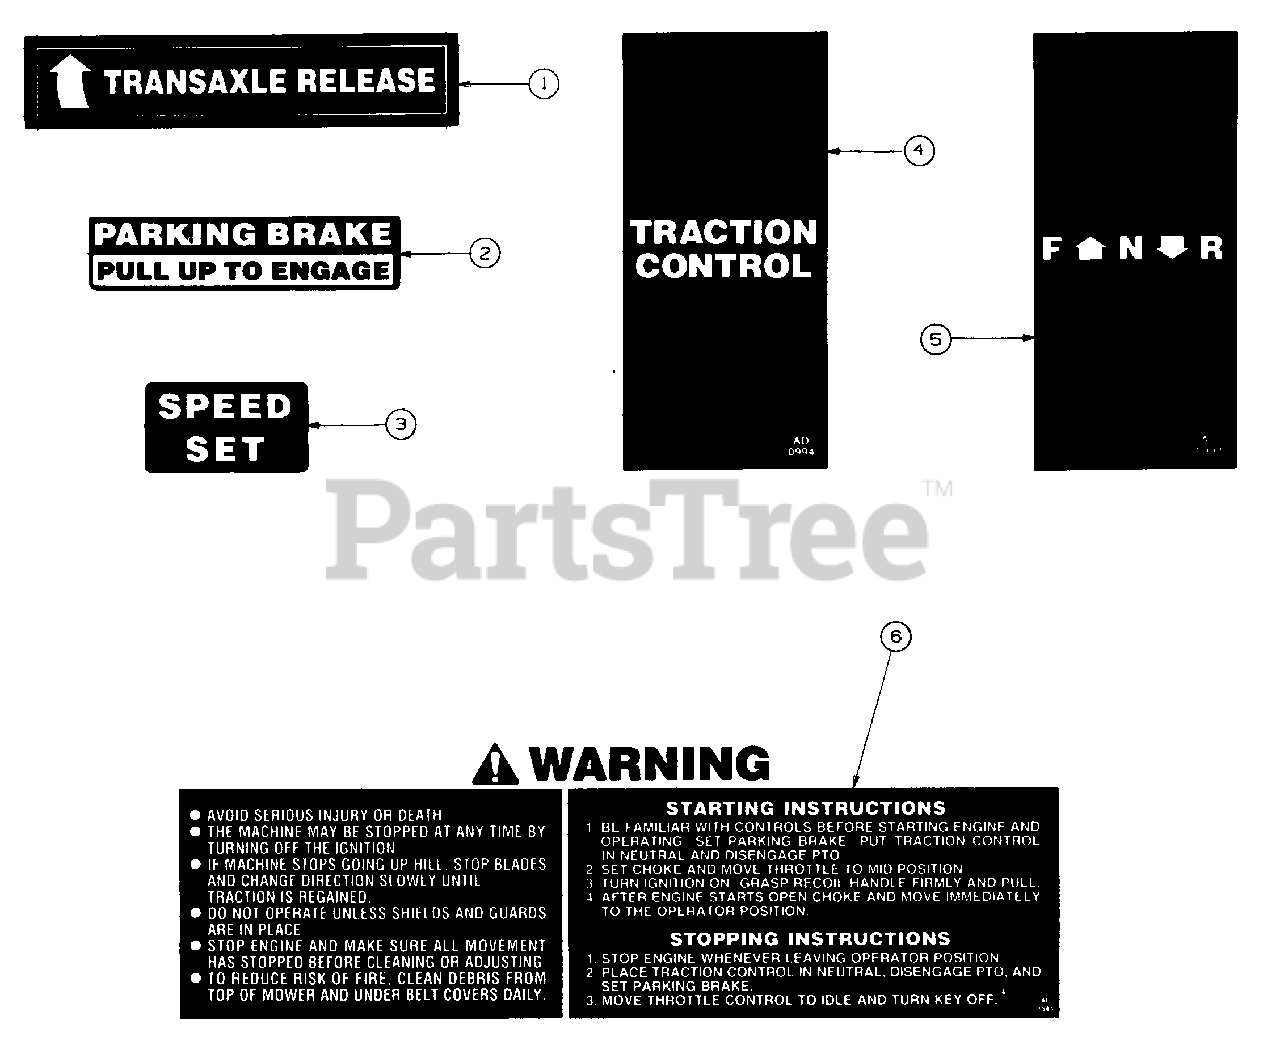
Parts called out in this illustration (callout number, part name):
1	Graphic, Transaxle Release
2	Graphic, Park Brake
3	Graphic, Speed Set
4	Graphic, Traction Control
5	Graphic, F-N-R
6	Graphic, Fuel Tank Warning
